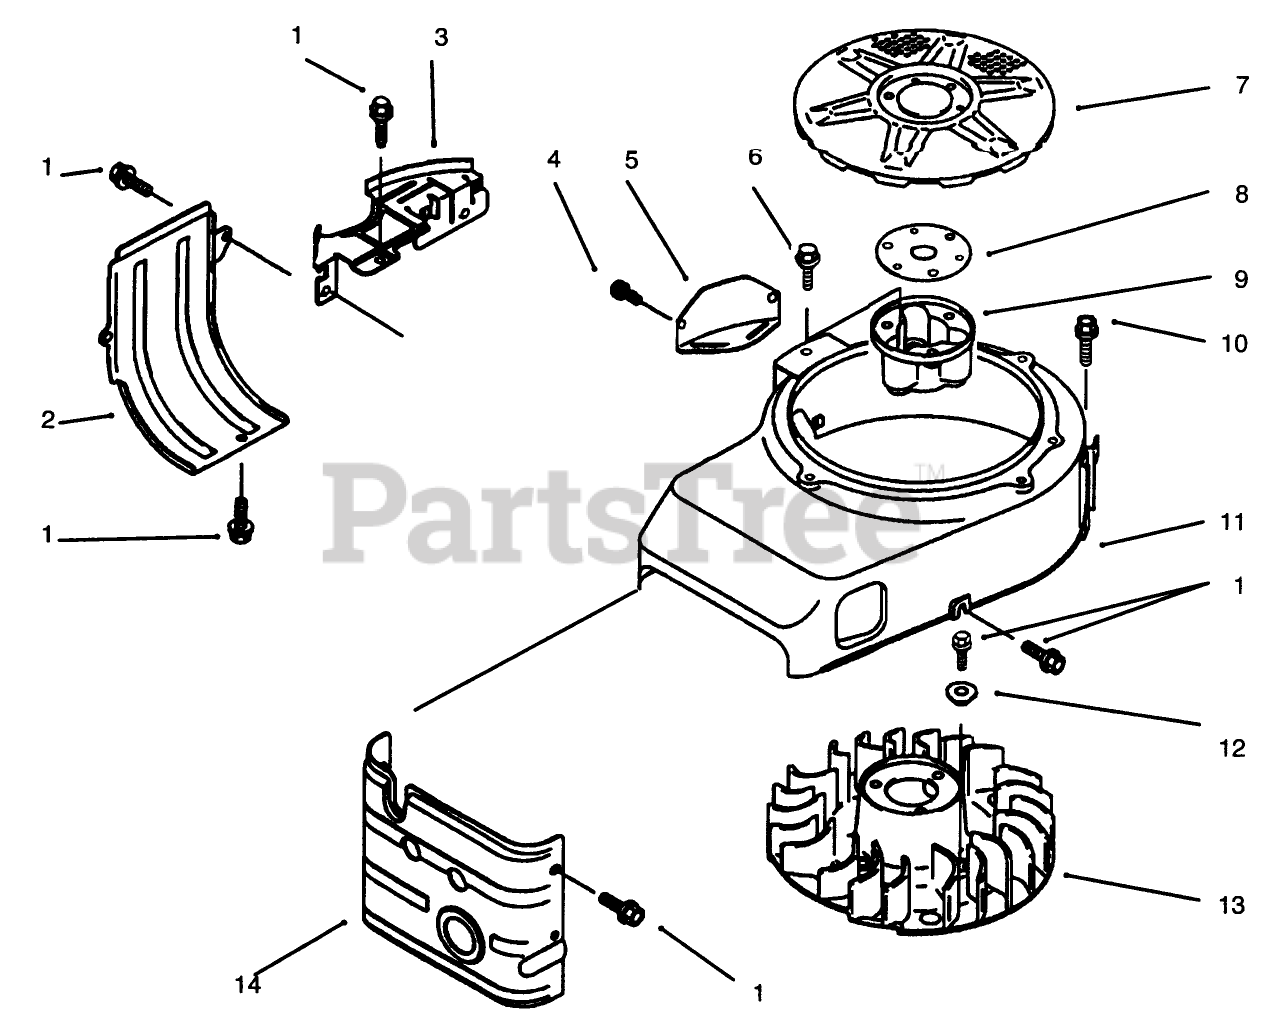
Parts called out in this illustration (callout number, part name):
1	Bolt-Flanged (6X10)
2	Shroud
3	Fan Housing
4	Screw
5	Cover
6	Bolt-Flange
7	Screen
8	Shim T-1.20
9	Bracket
10	Bolt-Flanged (6X14)
11	Housing-Fan
12	Collar
13	Fan
14	Shroud
